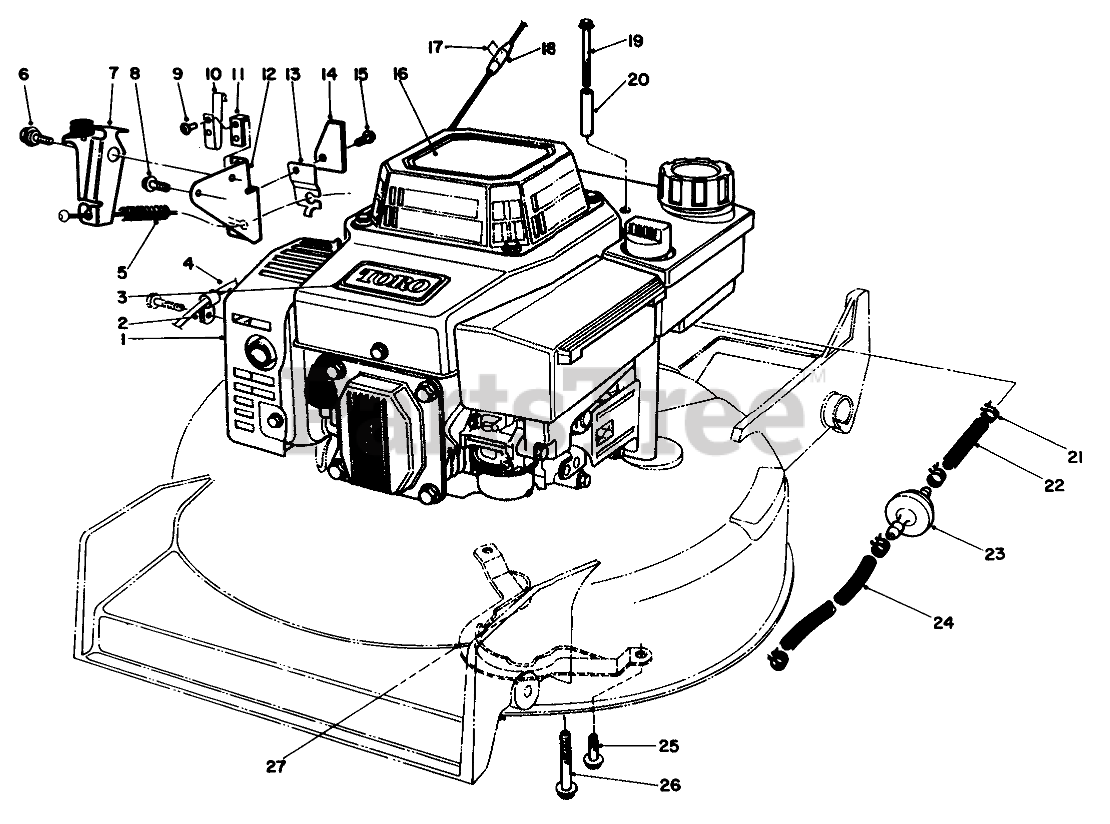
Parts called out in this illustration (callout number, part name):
1	Engine
2	CLIP-CLOSED, INSULATED
3	TORO LOGO PLT
4	ENGINE KILL WIRE
5	SPRING-COMPRESSION
6	Screw-Shoulder
7	BRAKE PLATE ASM
8	THO FORM SCREW M6 X 1
9	RIVET-PLASTIC
10	STRAP-GROUND
11	STRAP-INSULATING
12	Plate-Mounting
13	CABLE CLAMP
14	STOP-GROUND STRAP
15	SCREW
16	DECAL - OHV RECOIL
17	Staple
19	THRD FORMING SCREW
20	TUBULAR SPACER
21	CLAMP-FUEL LINE
22	LINE-GAS
23	FILTER-FUEL
24	HOSE-FUEL
25	SCREW-HWHTF
26	SCREW-HWHTF
27	Guide-Belt
